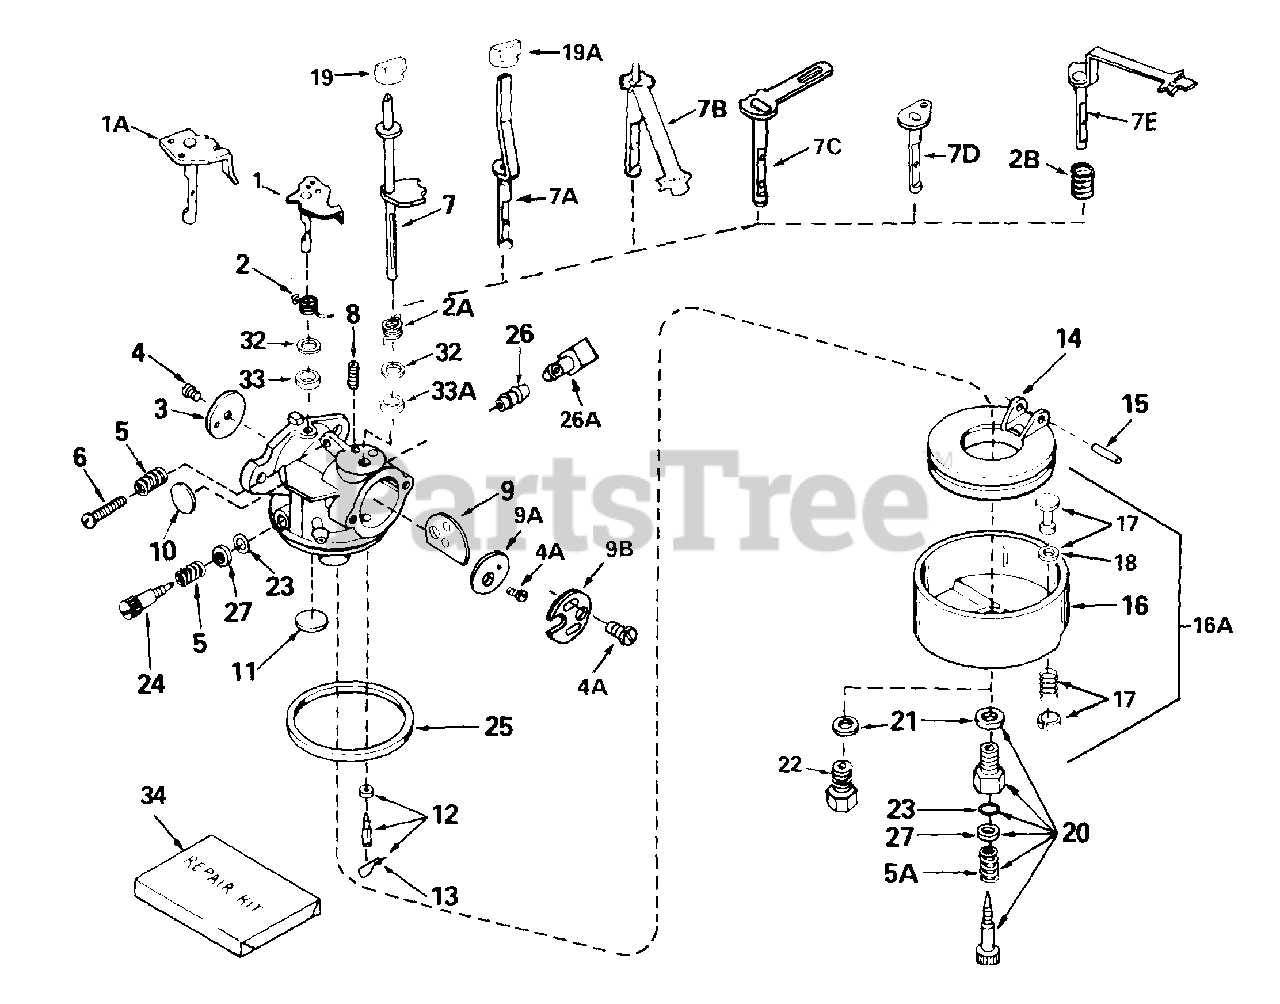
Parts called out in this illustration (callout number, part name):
1	"Shaft & Lever Assy., Throttle
2	Spring, Throttle return
3	Shutter, Throttle
4	Screw, Throttle shutter
4A	Screw, Choke shutter
5	Spring, Regulating screw
5A	Spring, Main adjustment screw
6	Screw, Idle regulating
7	Shaft, Choke (Plastic)
7A	Shaft, Choke (Metal)
8	Spring, Choke positioning
9	Shutter, Choke
9A	Shutter, Choke
10	Plug, Welch
11	Plug, Welch
12	Inlet Needle, Seat & Clip Assy.
13	Clip, Inlet needle
14	Float, Carburetor
15	Shaft, Float
16	Bowl, Float
19	Knob, Control
19A	Knob, Control
20	Adjustment Screw., Main
21	Gasket, Bowl-to-body
23	"O" Ring, Adjustment screw
24	Screw, Idle adjustment
25	Gasket, Bowl-to-body
26	Fitting, Fuel inlet
34	Repair Kit
